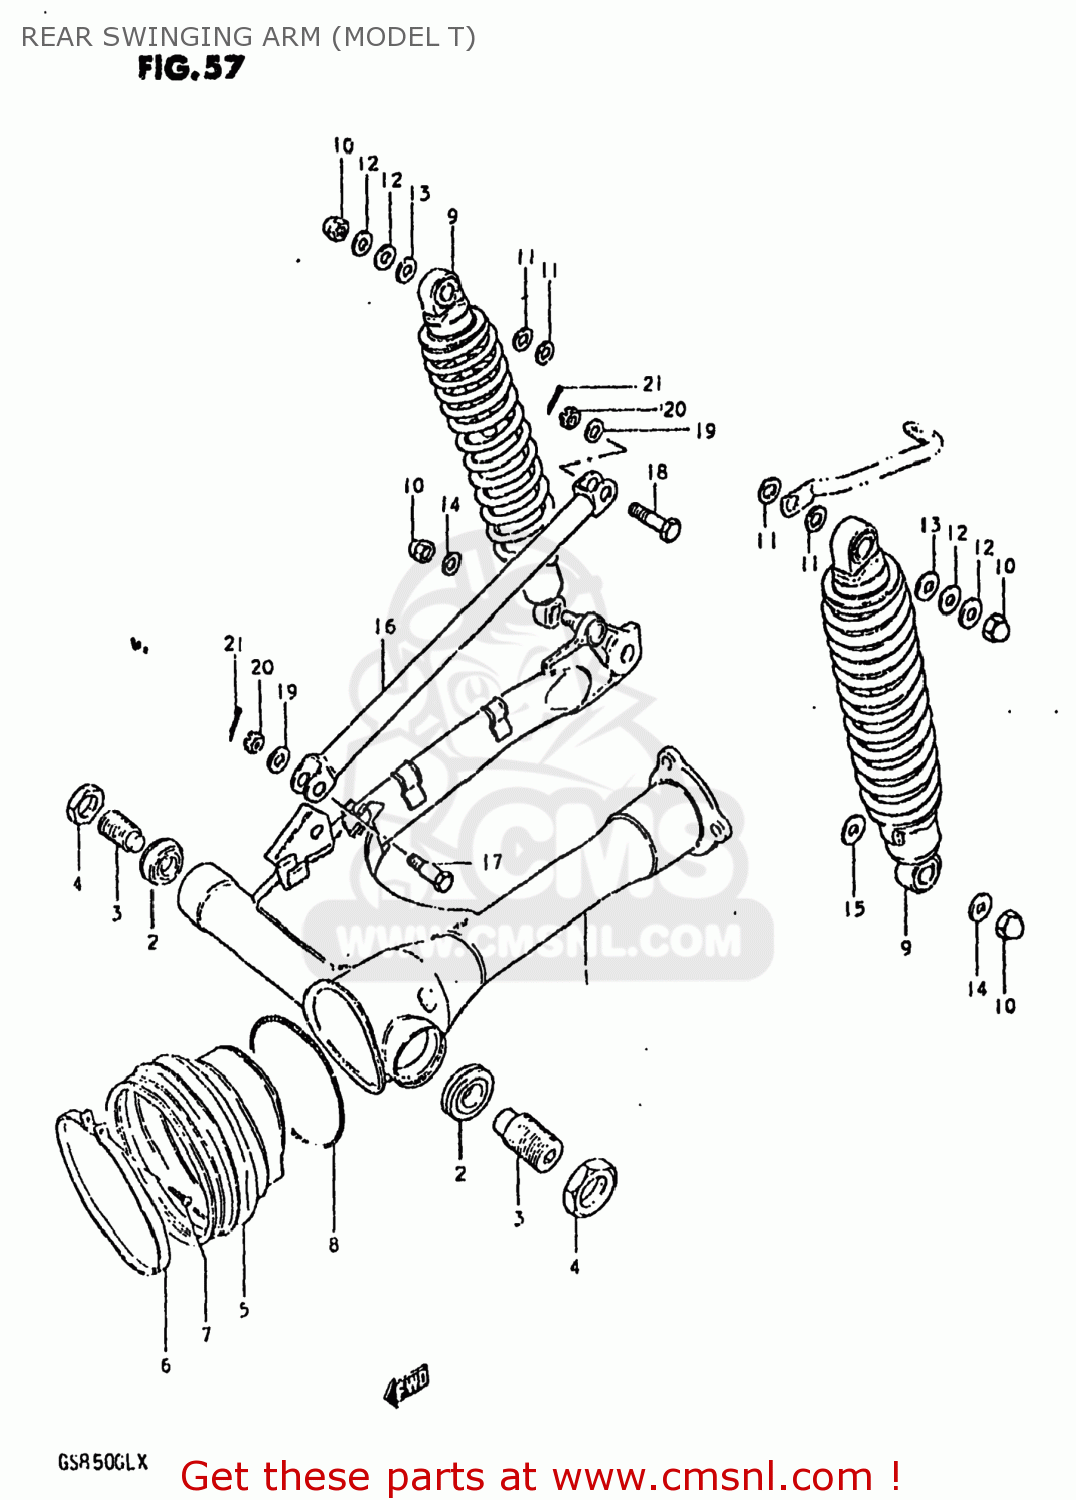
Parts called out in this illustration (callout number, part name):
1	SWING ARM ASSEMBLY,REAR
2	BEARING(17X40X13.25)
3	BOLT,REAR SWING ARM PIVOT
4	NUT
5	BOOT,PROPELLER SHAFT
6	CLAMP
7	SCREW 4X25
8	SPRING,PROPELLER SHAFT
9	ABSORBER ASSEMBLY,REAR SHOCK
10	NUT, LOWER LH
11	WASHER
12	WASHER
13	WASHER(10.5X24X3.2)
14	WASHER
15	WASHER
16	LINK,REAR TORQUE
17	BOLT
18	BOLT(10X39)
19	WASHER
20	NUT
21	PIN 20X20
